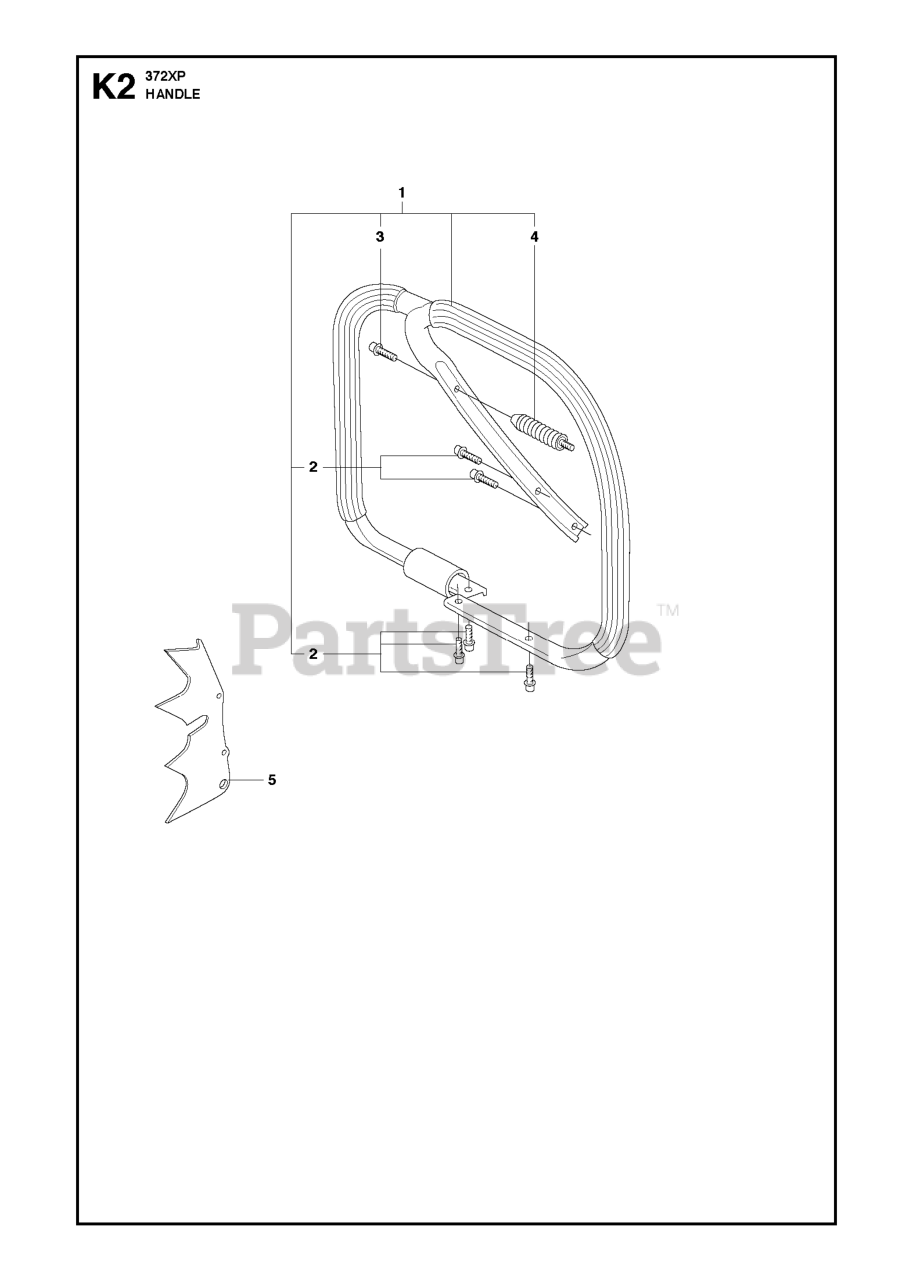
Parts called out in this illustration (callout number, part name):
1	FRONT HANDLE/WRAP
1	HANDLE, HTD WRAP 372
2	SCREW ITXSCFT PW5.5X16 T27 8.
3	SCREW ITXSCFT PW6.3X22 T27 8.
4	ANTIVIBRATION ELEMENT
4	VIBRATION ISOLATOR
5	FELLING DOG
